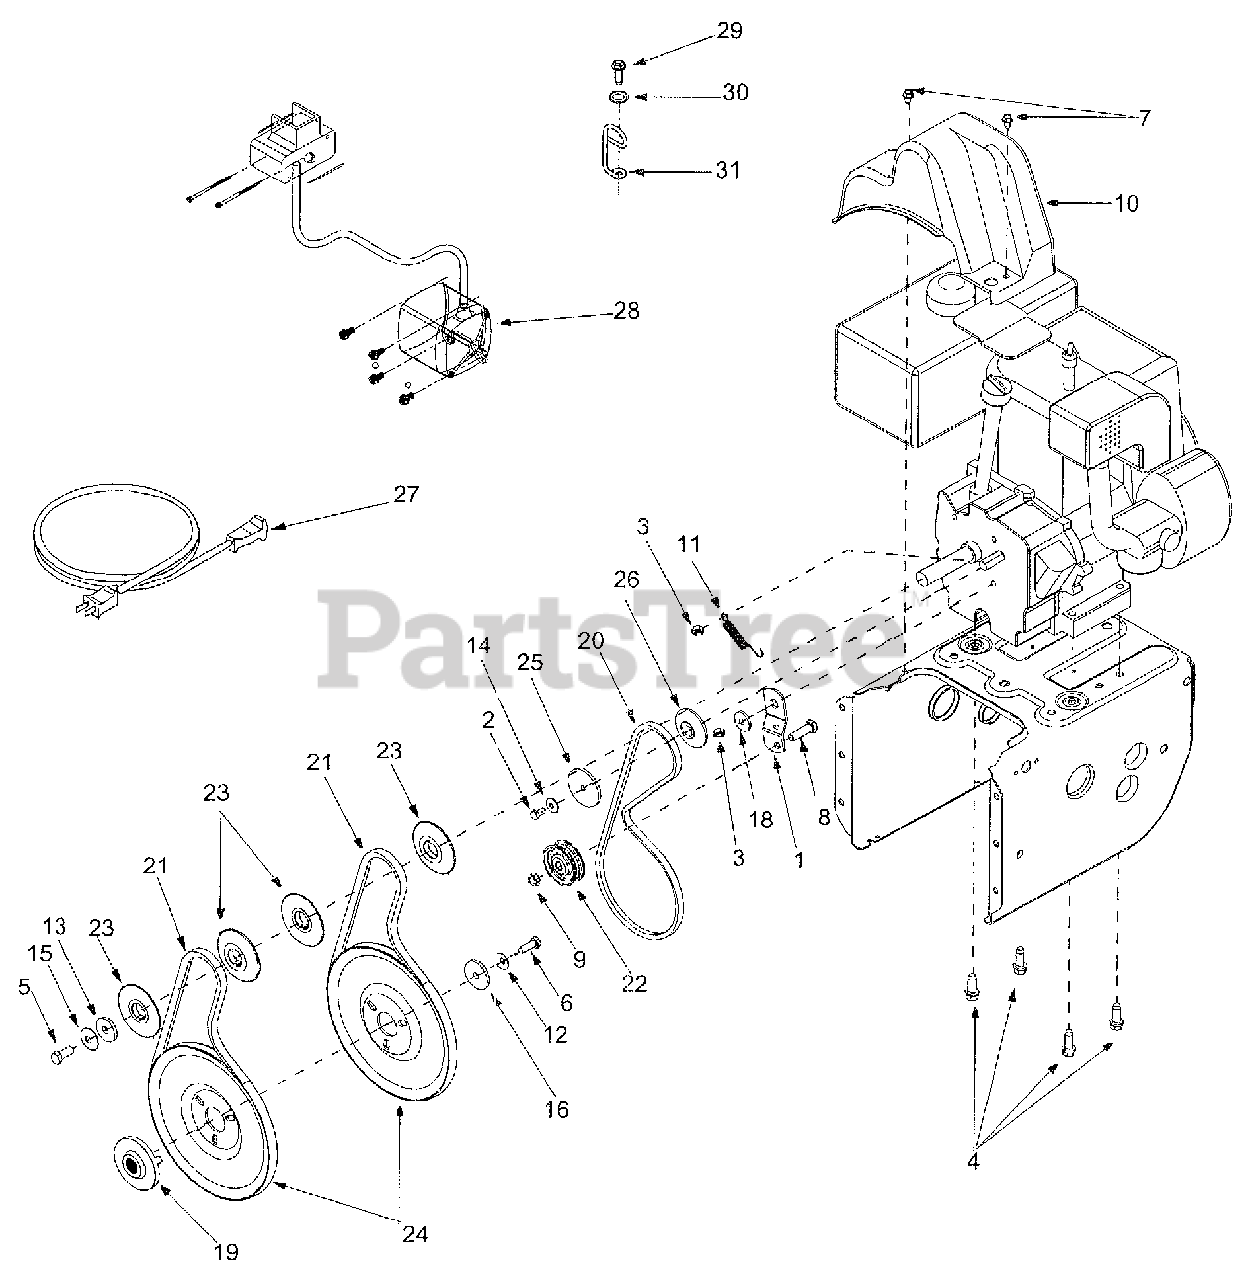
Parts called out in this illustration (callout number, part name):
3	Hex Scr w/ Patch: 5/16-24 x 0.75"
4	Hex Washer Head Sems Screw
5	Hex Bolt 3/8-24 x .875" Gr.8
6	Hex Scr w/ Patch: 5/16-24 x .875"
7	Hex Washer Head TT
8	Hex Screw: 3/8-16 x 1.0"
9	Top Lock Jam Nut: 3/8-16
11	Extension Spring
12	Bellevile Washer
18	Shoulder Spacer
19	Adapter Pulley
20	V -Belt
21	Belt
24	Auger Pulley
26	Pulley Half
27	Extension Cord
28	Electric Start Kit
29	Lock Nut 1/4-20
30	Flat Washer.28 ID x .74 OD
